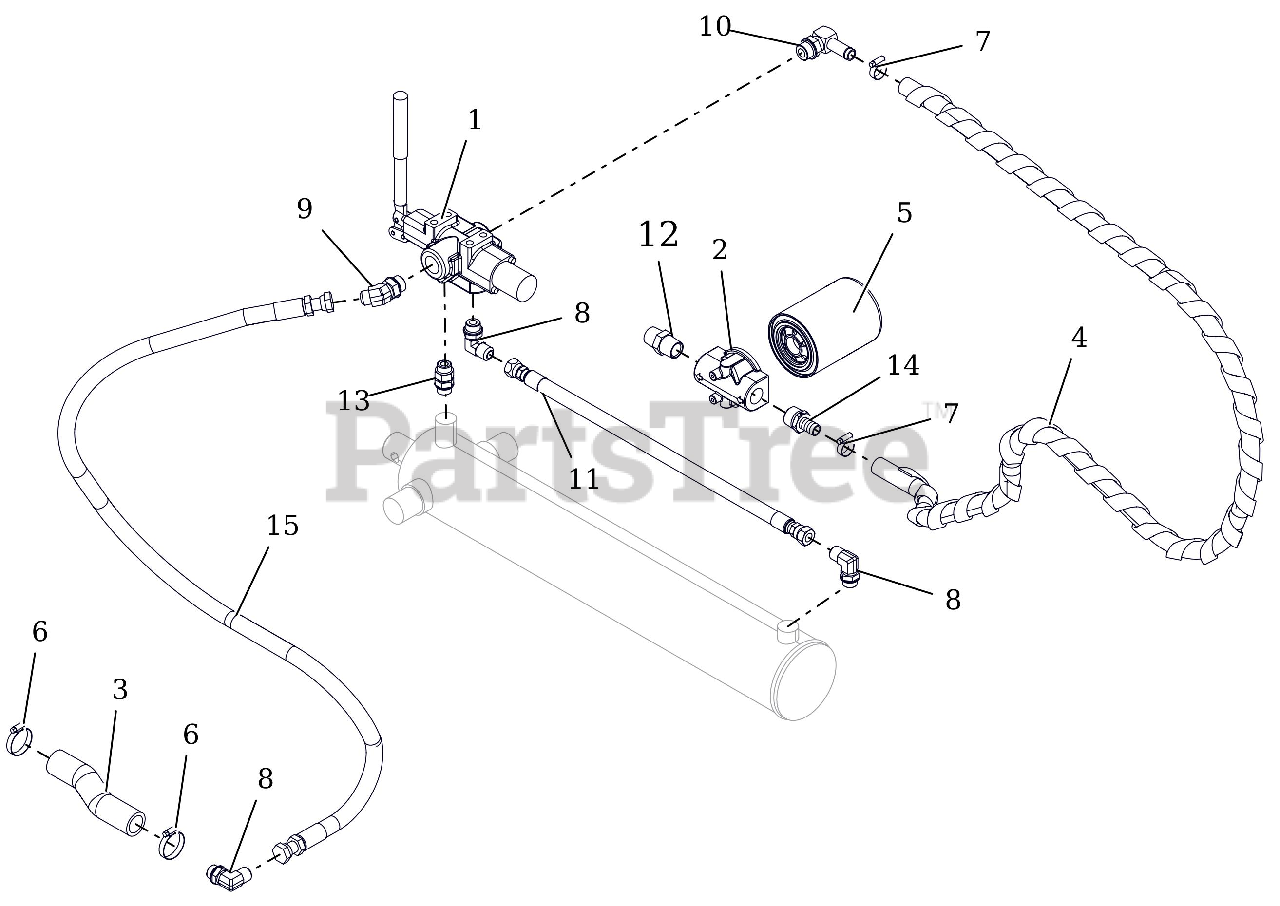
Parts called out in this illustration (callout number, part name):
1	VALVE CONTROL-SPLITTER
2	HEAD,FILTER-3/4 NPT BYPASS
3	HOSE, HYD - SUCTION 7.375"
4	HOSE, HYD-RET 801-10 WP 74"
5	FILTER,HYDRAULIC OIL-NO BYPASS
6	CLAMP-HOSE 1.50X.81X1.42
7	CLAMP,.88 DIA. HOSE
8	FTG,HYD 6801-8-8
9	FTG,HYD 6802-8-10
10	FTG,HYD 4601-10-10
11	HOSE, HYD - 22"
12	FTG,HYD 5404-12-12
13	FTG, HYD - STR 08MAORB-08MORB
14	FTG,HYD STRAIGHT 10-12
15	HOSE, HYD - 58"
